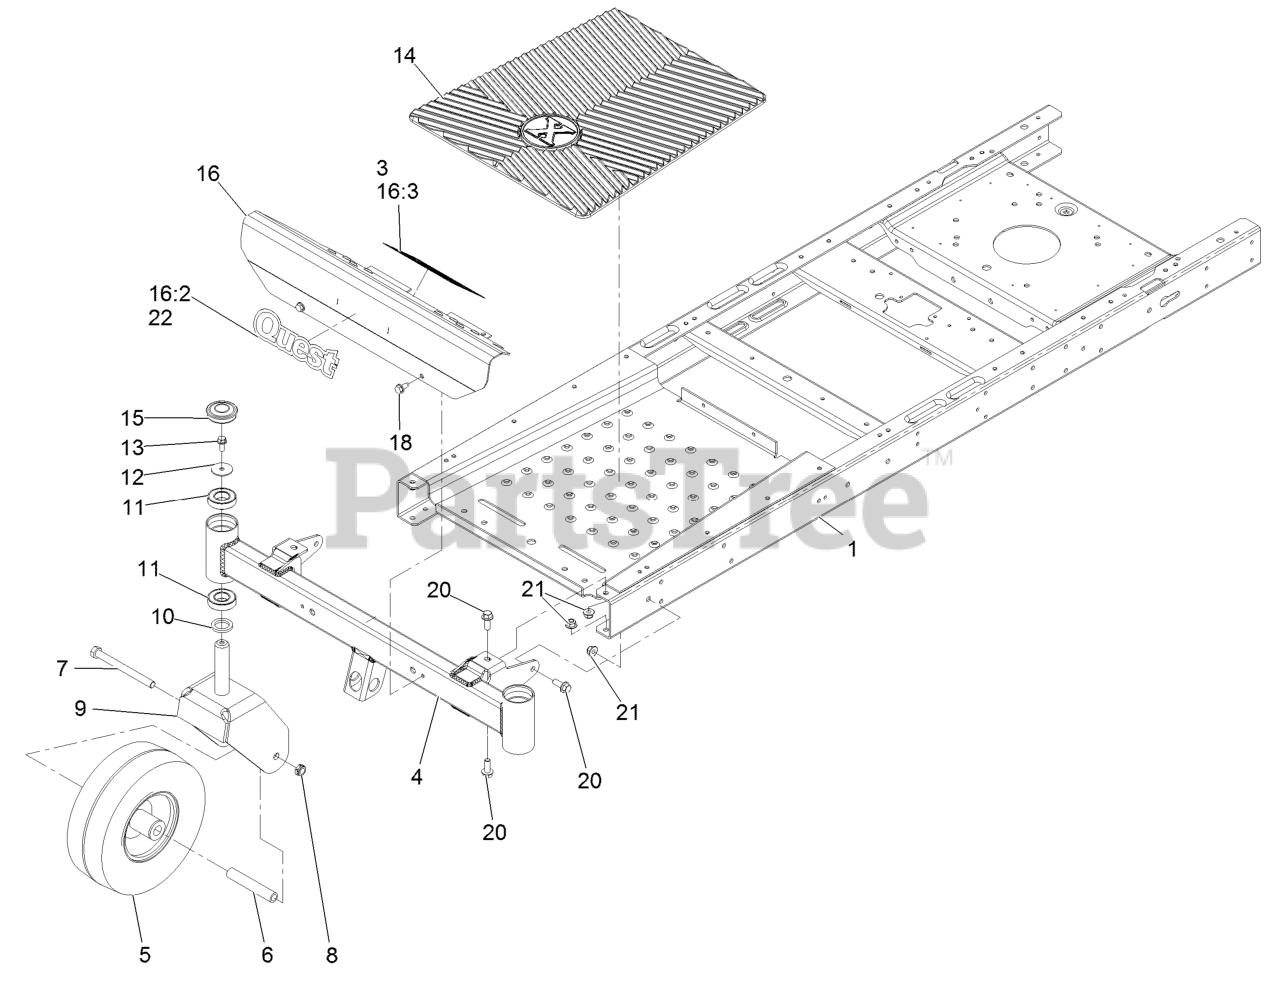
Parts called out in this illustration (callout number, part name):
1	FRAME ASM
3	DECAL-DANGER
4	AXLE-FRONT, NARROW
5	CASTER WHEEL ASM
6	BUSHING-SPANNER
7	SCREW-HH
8	NUT-HEX
9	FORK-CASTER
10	WASHER-THRUST
11	BEARING-BALL
12	WASHER-FLAT
13	SCREW-HHF
14	MAT-FLOOR
15	CAP-GREASE
16	FOOTREST ASM
16:3	DECAL-DANGER
18	Screw-HWH 5/16-18 X 3/4 Tf
20	SCREW-HHF 3/8-16 X 1
21	NUT-HF, NI
